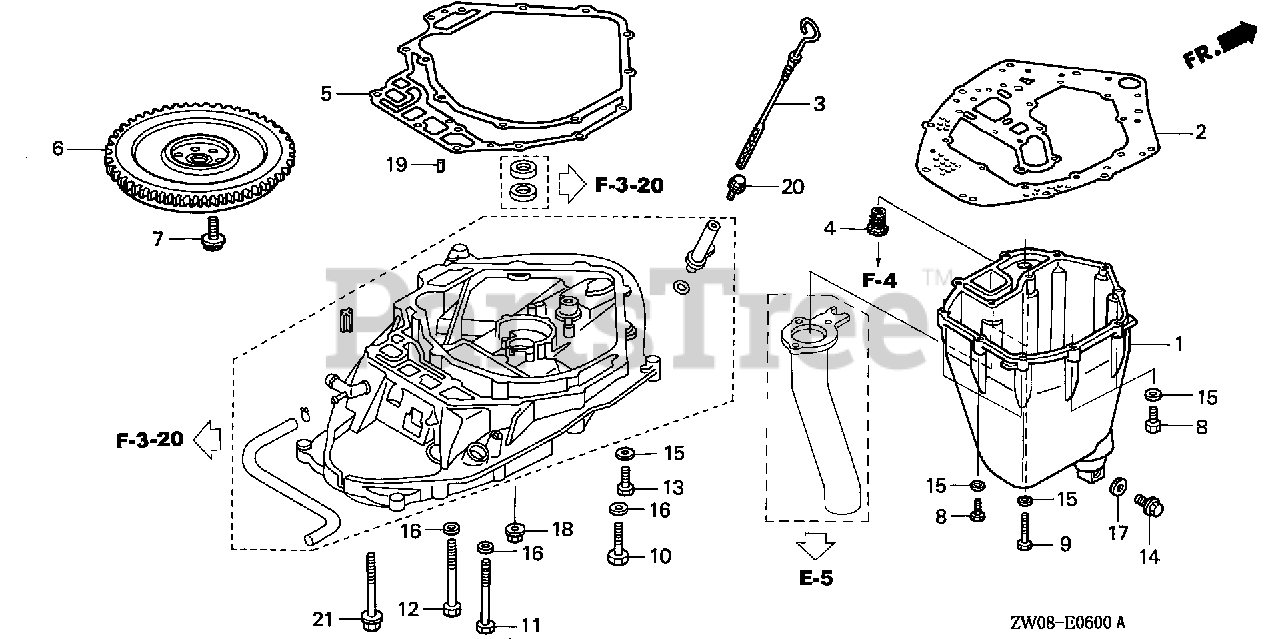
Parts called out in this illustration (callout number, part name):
1	PAN, OIL *TGRAY* (GRAY)
2	GASKET, OIL PAN
3	DIPSTICK, OIL
4	GROMMET, WATER TUBE
5	GASKET, MOUNT CASE
6	FLYWHEEL *TBLACK* (BLACK)
7	BOLT (12MM)
8	BOLT, HEX. (8X35) Use up to Frame SN 4800712.
9	BOLT, HEX. (8X55)
10	BOLT, HEX. (10X47)
11	BOLT, HEX. (10X110)
12	BOLT, HEX. (10X90)
13	BOLT, HEX. (8X25)
14	BOLT, DRAIN PLUG
15	WASHER, PLAIN (8MM)
16	WASHER, PLAIN (10MM)
17	WASHER, DRAIN PLUG (12MM)
18	NUT, FLANGE (10MM)
19	PIN, DOWEL (6X10)
20	BOLT, FLANGE (6X12)
21	BOLT, FLANGE (10X110)
